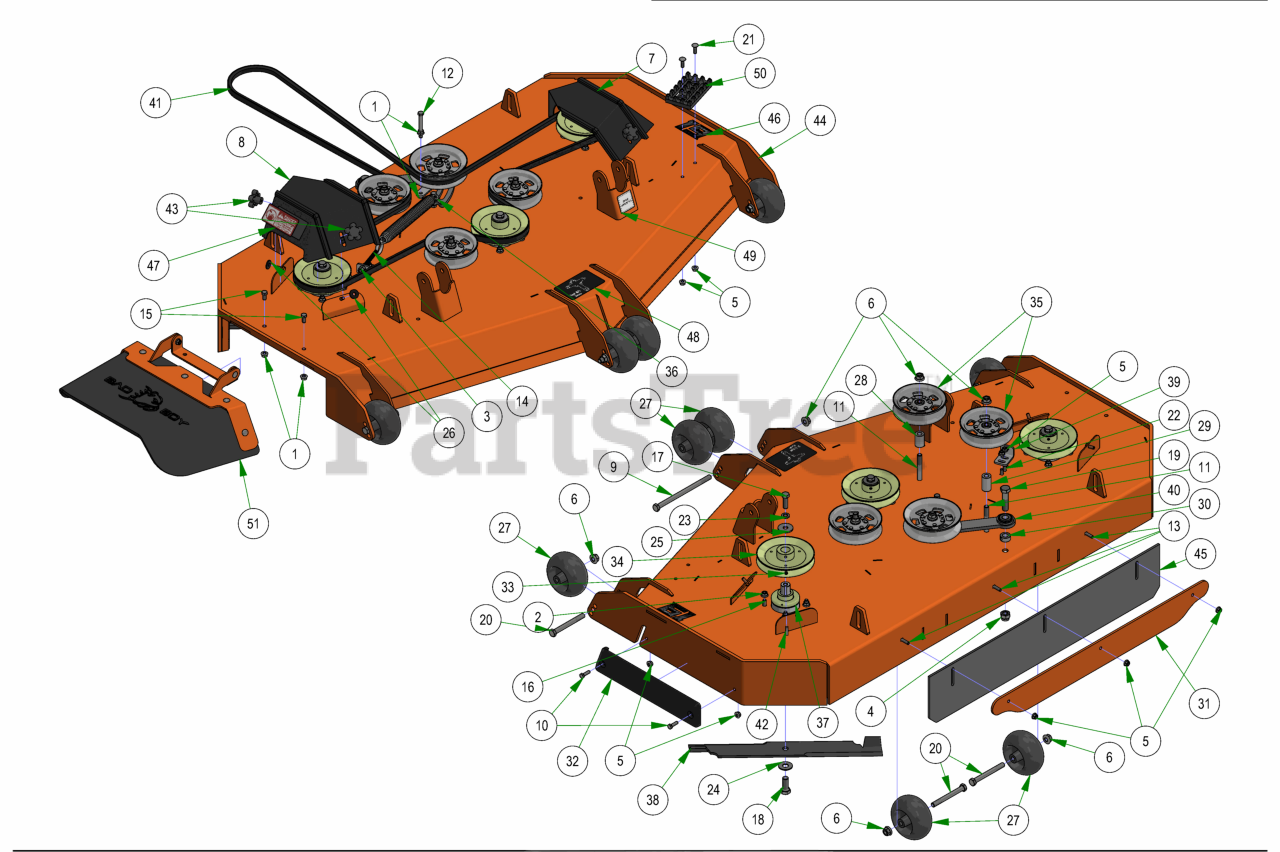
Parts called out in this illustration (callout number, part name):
1	3/8-16 HEX SERRATED FLANGE NUT HARD/ZINC
2	3/8-16 NYLON INSERT FLANGE LOCKNUT (GR.F) ZINC
3	3/8-16 HEX NUT ZINC
4	5/8-11 NYLON INSERT LOCKNUT ZINC
5	5/16-18 NYLON INSERT FLANGE LOCKNUT ZINC
6	1/2-13 NYLON INSERT FLANGE LOCKNUT ZINC
7	2019 61" Outlaw Gen2 Pulley Cover Left
8	2019 61" Outlaw Gen2 Pulley Cover Right
9	1/2-13 X 8 HEX CAP SCREW GR 5 ZINC
10	5/16-18 X 1 HEX CAP SCREW (GR.5) ZINC
11	1/2-13 X 3-1/2 HEX FLANGE BOLT (GR.8) ZINC
12	3/8-16 X 3 HEX CAP SCREW (GR.5) ZINC
13	5/16-18 X 1-1/4 CARRIAGE BOLT ZINC
14	4" 3/8-16 Eye Bolt
15	3/8-16 X 3/4 HEX CAP SCREW (GR.5) ZINC
16	3/8-16 X 1-1/2 HEX CAP SCREW (GR.5) ZINC
17	1/2-20 X 1-1/2 HEX CAP SCREW (GR.5) ZINC
18	5/8-18 X 1-1/2 HEX CAP SCREW (GR.8) ZINC YELLOW
19	5/8-11 X 2-1/2 HEX CAP SCREW (GR.5) ZINC
20	1/2-13 X 4-1/2 HEX CAP SCREW (GR.5) ZINC
21	5/16-18 X 1 CARRIAGE BOLT (GR.8) ZINC
22	5/16-18 X 7/8 CARRIAGE BOLT ZINC
23	1/2 SPLIT LOCKWASHER (GR.8) ZINC/YELLOW
24	5/8 USS FLAT WASHER (1-3/4" OD) GR.8 ZINC YELLOW
25	1/2 BELLEVILLE WASHER (1-5/8 OD X .140 THK) ZINC
26	.360 ID X .983 OD X .120 THICK FLAT WASHER NYLON BLACK
27	2019 Deck Wheel
28	.502 ID X .750 OD X 1.500 Long Spacer
29	1 3/4" Pulley Spacer
30	5/8 SOLID SHAFT COLLAR (W/1 SET SCREW) ZINC
31	61 Bolt in Baffle Deck v2 Stripping Plate
32	REVISED TRIM BUMPER_20180226
33	5/16-24 X 1/4 SOCKET SET SCREW (CUP PT) PLAIN
34	6 1/4" Drive Pulley
35	5-3/4 Idler Pulley
36	2019 Outlaw Gen2 Deck Spring
37	OUTLAW SPINDLE ASSEMBLY
38	61" High Lift Fusion Blade
39	2019 Deck Eye Bolt Tab
40	2019 Rebel Rogue Deck Idler
42	1/4 X 1 SQ MACHINERY KEY 1018 STL PLN
43	5/16" Knob
44	2019 Sloped 61" Deck
45	R Series Rubber For Deck
46	61" Deck Decal
47	Danger Decal-Spindle/Discharge
48	2019 Rebel & Rogue Deck Belt Route Decal
49	Deck Impact Patent Decal 9591803
50	Deck Step Assembly
51	2019 Outlaw Gen2 Chute Assembly
